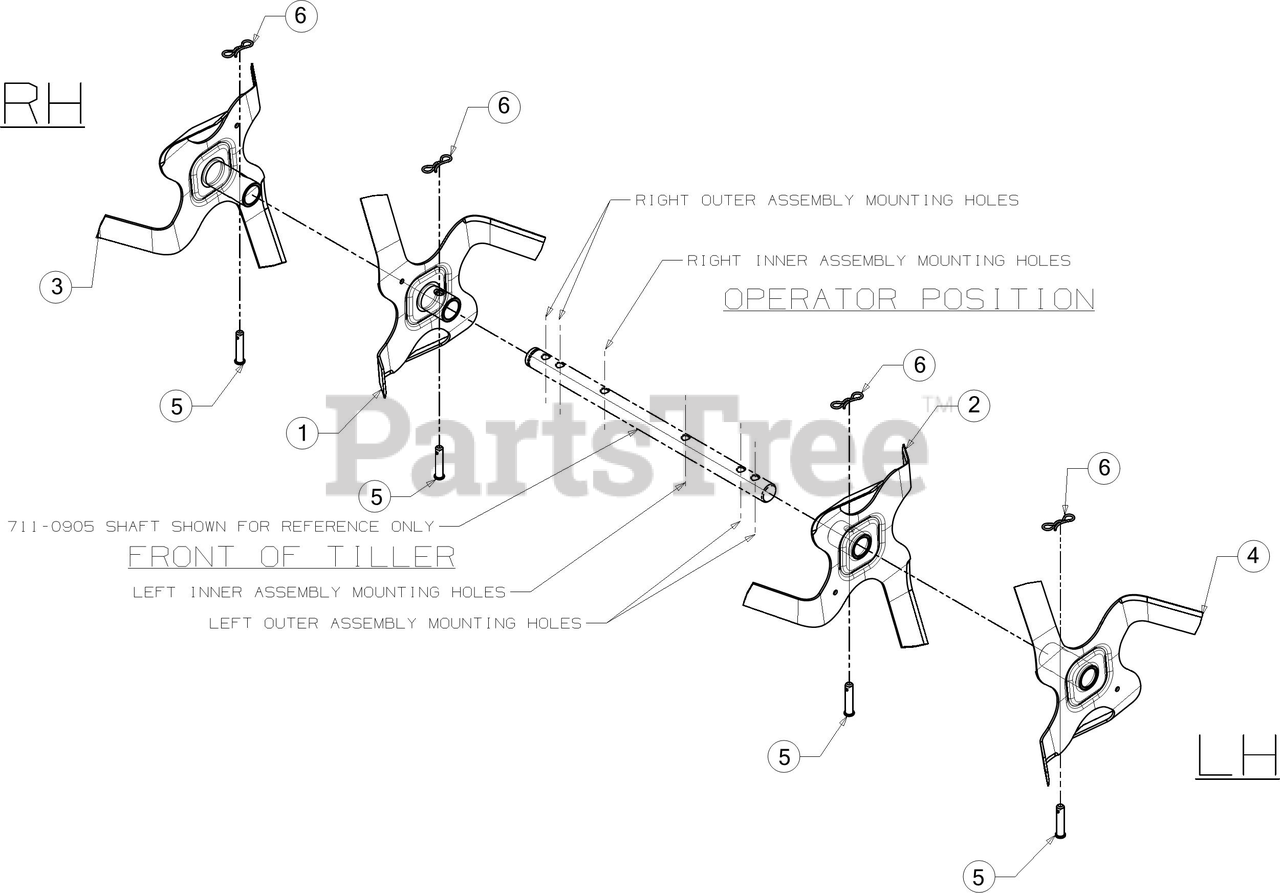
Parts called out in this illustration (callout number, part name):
1	TINE ASSEMBLY (INNER) (RH)
2	TINE ASSEMBLY (INNER) (LH)
3	TINE ASSEMBLY (OUTER) (RH)
4	TINE ASSEMBLY (OUTER) (LH)
5	CLEVIS PIN .375 X .1.75
6	PIN:COTTER
7	GREASE
